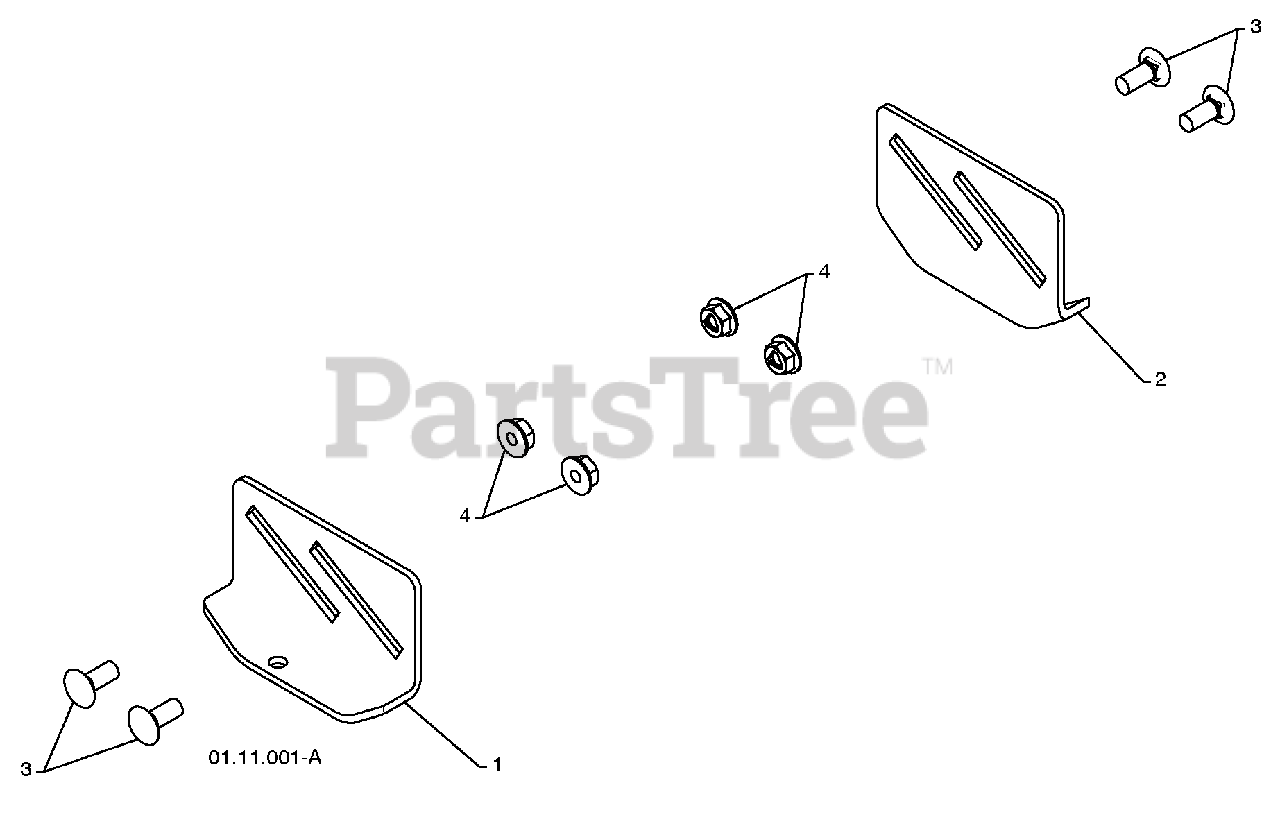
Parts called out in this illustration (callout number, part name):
1	SKID PLATE LH
2	SKID PLATE RH
3	CARRIAGE BOLT 5/16-18 X .75
4	NUT 5/16-18
